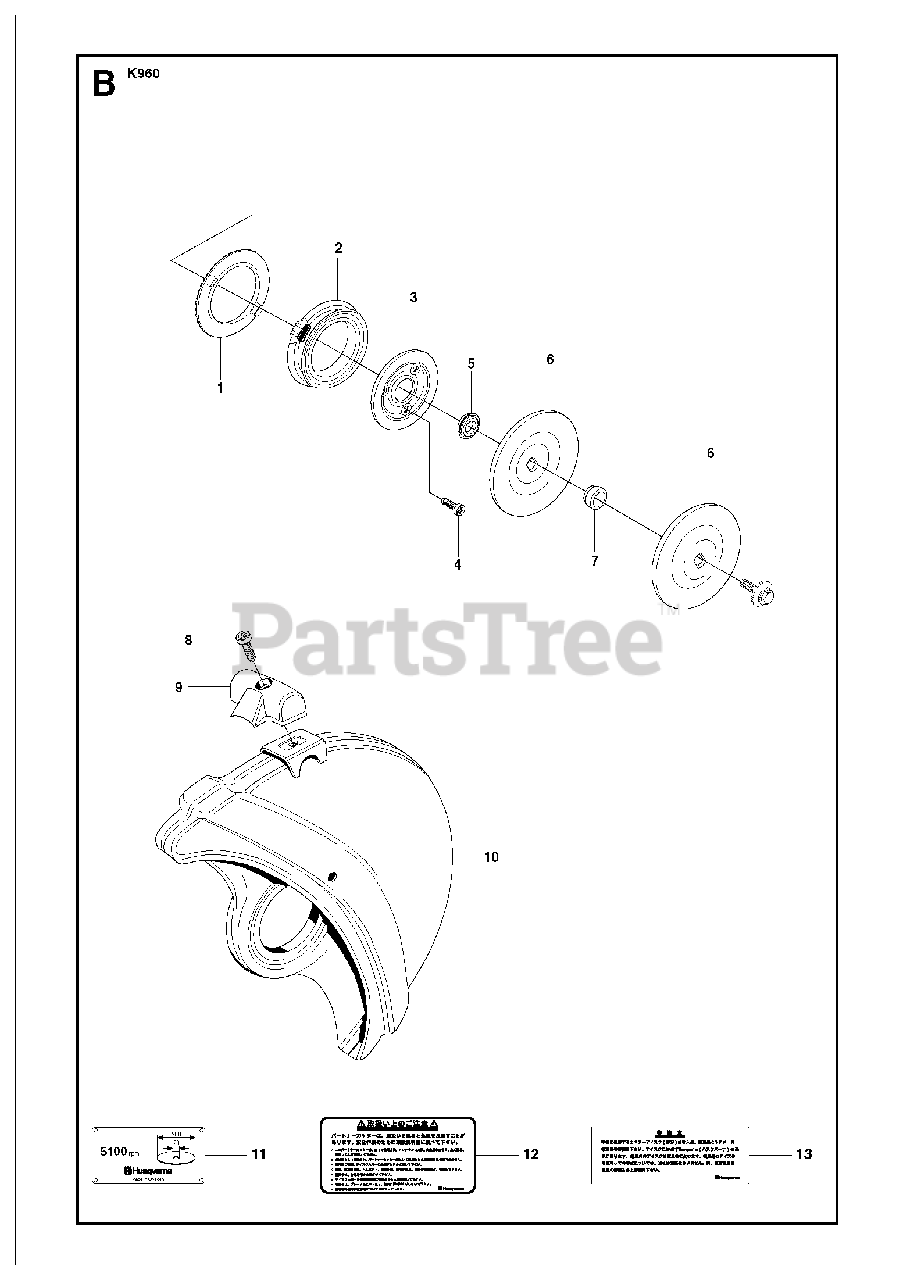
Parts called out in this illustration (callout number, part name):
4	SCREW ITXSCM
5	SUPPORT FLANGE
6	FLANGE WASHERDiam 105
6	FLANGE WASHERDiam 116
7	KITDiam 22,2
7	BUSHINGDiam 30,5
8	SCREW ITXSCM
10	BLADE GUARD"12"". Incl. 2, 9, 10"
10	BLADE GUARD"14"". Incl. 2, 9, 10"
10	BLADE GUARD"16"". Incl. 2, 9, 10"
11	LABEL"12"". Diam 1"""
11	LABEL"12"". Diam 20 mm"
11	LABEL"14"". Diam 1"""
11	LABEL"14"". Diam 20 mm"
11	LABEL"16"". Diam 1"""
11	LABEL"16"". Diam 20 mm"
